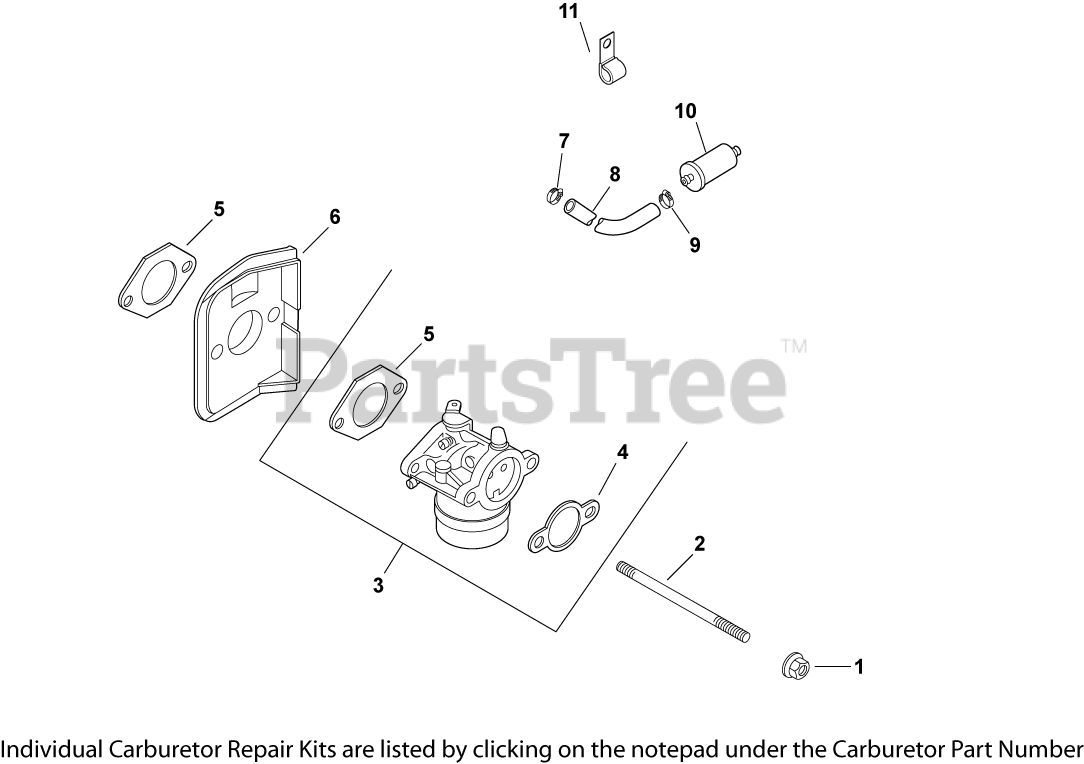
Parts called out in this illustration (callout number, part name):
1	NUT, FLG M6X1.0
2	STUD,M6X1.0X116
3	KIT, CARB W/GASKETS - USE 12 853 177-S
4	GASKET, AIR CLEANER BASE
5	GASKET, CARBURETOR
6	DEFLECTOR, HEAT
7	CLAMP, HOSE (KM)-USE 25 237 31-S
8	HOSE,LW PERM.FUEL 24.00"-USE 25 111 81-S
9	CLAMP, BAND SPRING HOSE-(#2523737S)
10	FILTR,FUEL 75 MICRON (GRAVTY FEED)
11	CLIP, CABLE
